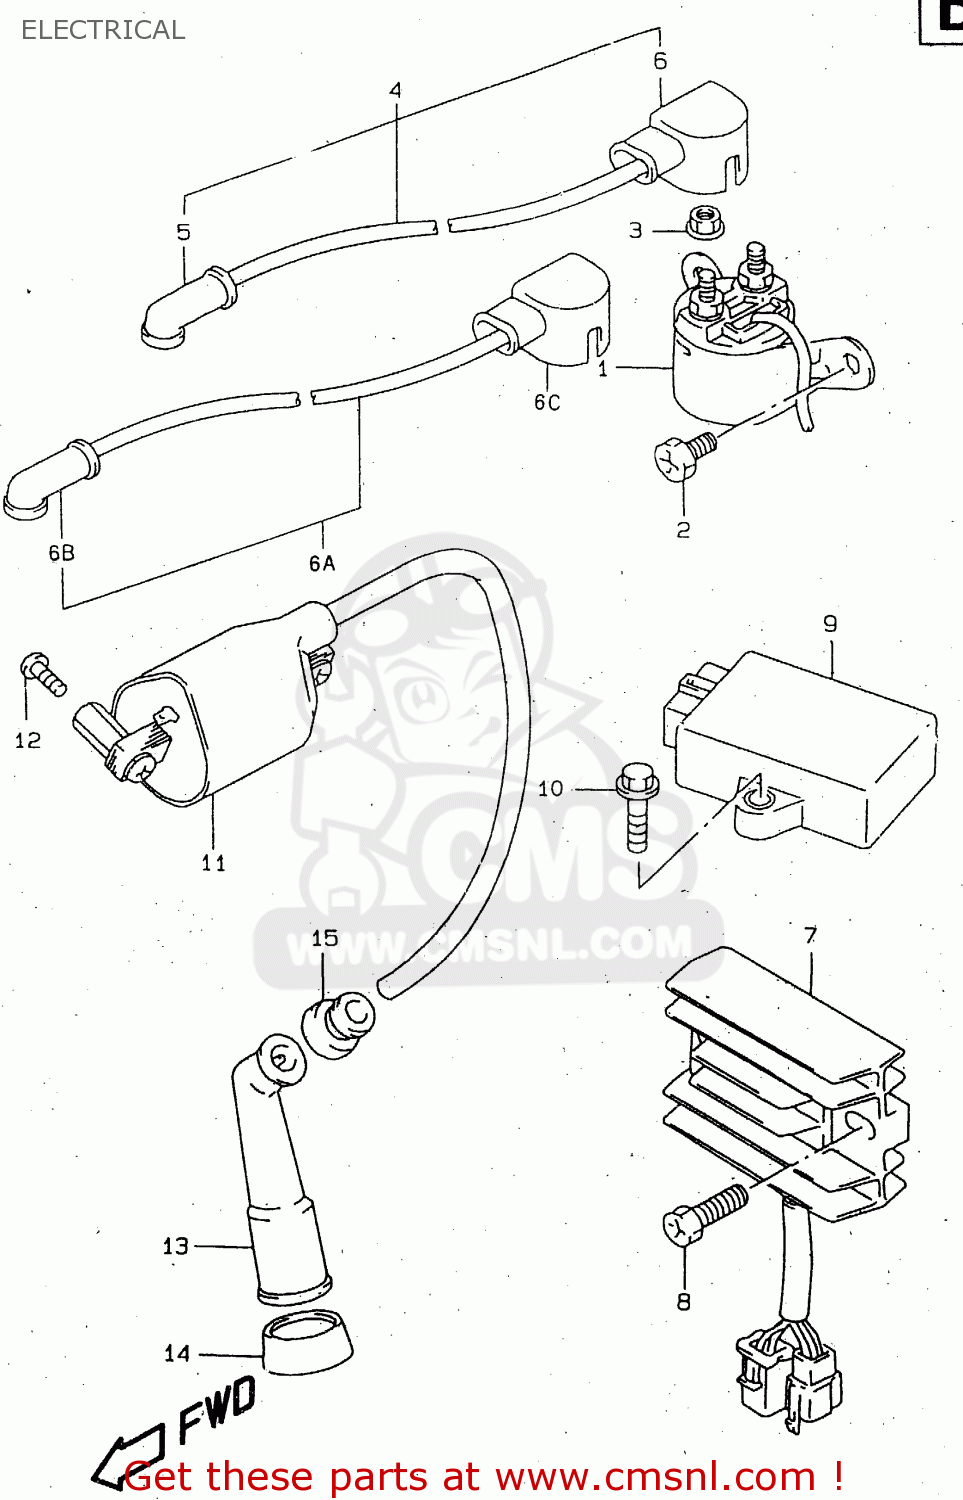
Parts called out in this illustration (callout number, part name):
1	RELAY ASSY,STARTING MOTOR
2	SCREW(6X10)
3	NUT
4	WIRE,STRT.LEAD
5	CAP,STARTER MOTOR LEAD
6	CAP,STARTER RELAY TERMINAL
6A	WIRE,STARTER MOTOR LEAD
6B	CAP,STARTER MOTOR LEAD
6C	CAP,STARTER RELAY TERMINAL
7	RECTIFIER ASSY
8	BOLT(6X20)
9	IGNITOR UNIT
10	BOLT
11	COIL ASSY,IGNITION
12	SCREW
13	CAP ASSY,SPARK PLUG
14	SEAL,SPARK PLUG CAP
15	SEAL,HIGH TENSION CORD
